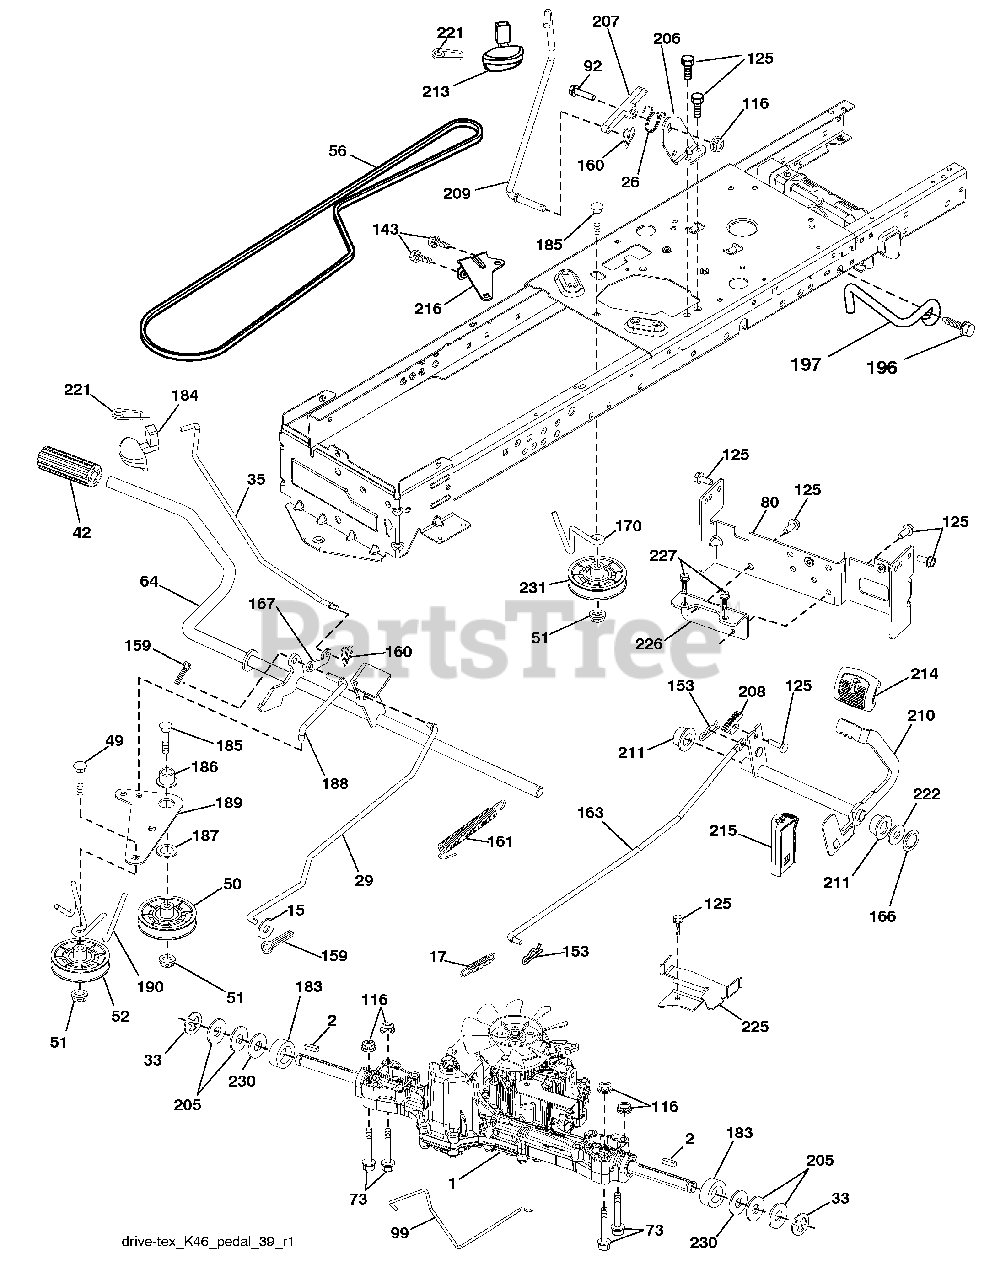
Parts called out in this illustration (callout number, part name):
15	Washer 13/32 x 13/16 x 16 Ga.
17	Spring, Brake
26	Spring Return Cruise
29	Rod, Brake
35	Rod, Brake, Park
42	Cover, Foot Pedal
50	Pulley Idler Flat
51	Lock Nut 3/8-16
52	Idler V-Groove 910" Offset
56	V-Belt, Drive
64	Shaft Asm. Pedal Brake Control
73	Bolt 5/16-18 Gr. 5
80	Strap Torque
92	Bolt Fin Hex 5/16-18 unc x 1.25
99	Spring Rod Bypass
116	Nut Lock Hex Flange 5/16-18
125	Screw 5/16-18 x 3/4
143	Screw Thdrol 5/16-18 x 1/2
153	Retainer Spring
159	Pin Cotter 1/8 x 3/4
160	Retainer Clip
161	Spring, Return, Clutch
163	Rod Pedal Control
166	Nut Push .625
167	Latch Brake Parking
170	Keeper Belt Centerspan
183	Spacer Split
184	Handle Parking Brake
185	Bolt 3/8 - 16 x 2-3/4 Gr. 5
186	Spacer Retainer
187	Washer
188	Link Clutch Ground Drive
189	Bellcrank Ground Drive
190	Keeper Bellcrank Ground Drive
196	Screw 3/8-16 x 1
197	Bracket Clutch Anti-Rotation
206	Bracket Mount Latch Cruise
207	Latch Control Cruise
208	Gear Sector Control Cruise
209	Rod Control Cruise
210	Rocker Asm. Pedal Control
211	Bearing Nylon
213	Knob Control Cruise
214	Pedal Forward
215	Pedal Reverse
216	Bracket Pulley Idler
221	Retainer Spring Clip Handle
222	Washer 21/32 x 1-1/4 x 10 Ga.
225	Keeper Belt Trans.
226	Bracket Mount Touque
227	Screw Thdrol 5/16-18 x 3/4
231	Idler V-Groove Pulley
